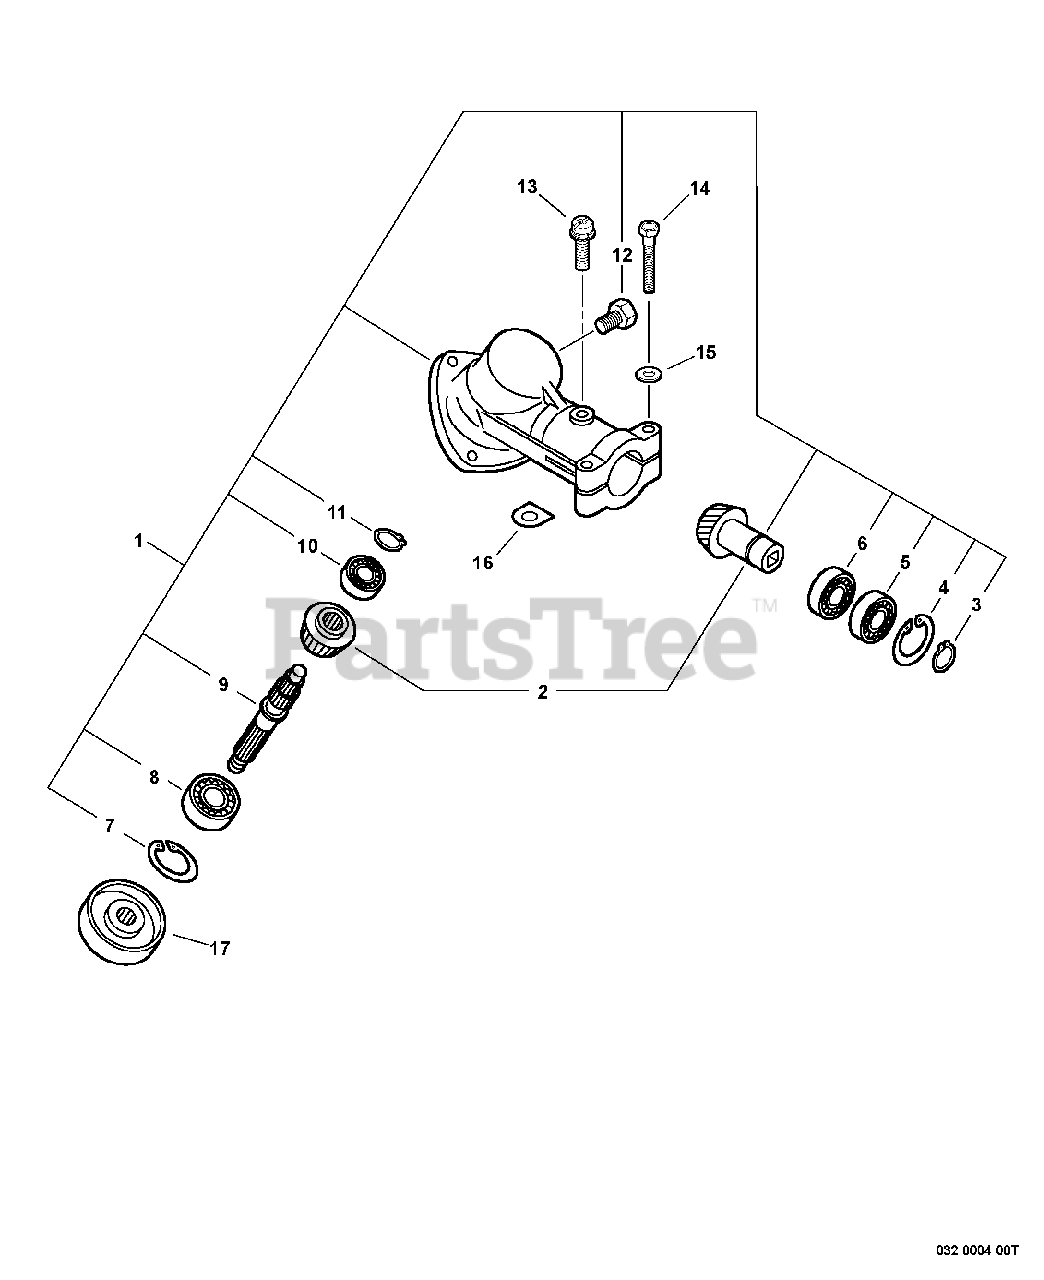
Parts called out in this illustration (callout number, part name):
1	GEAR CASE ASSY
2	GEAR SET
3	RING, SNAP Ø10
4	RING, SNAP Ø22
5	BEARING, BALL 6900Z
6	BEARING, BALL 6900
7	RING, SNAP Ø42
8	BEARING, BALL 629
9	SHAFT, GEAR
10	BEARING, BALL 6302
11	RING, SNAP Ø12
12	BOLT M8×8
13	SCREW 5×12
14	BOLT 5×30
15	WASHER, FLAT 5.5×10×0.8
17	PLATE, ADAPTOR - UPPER
